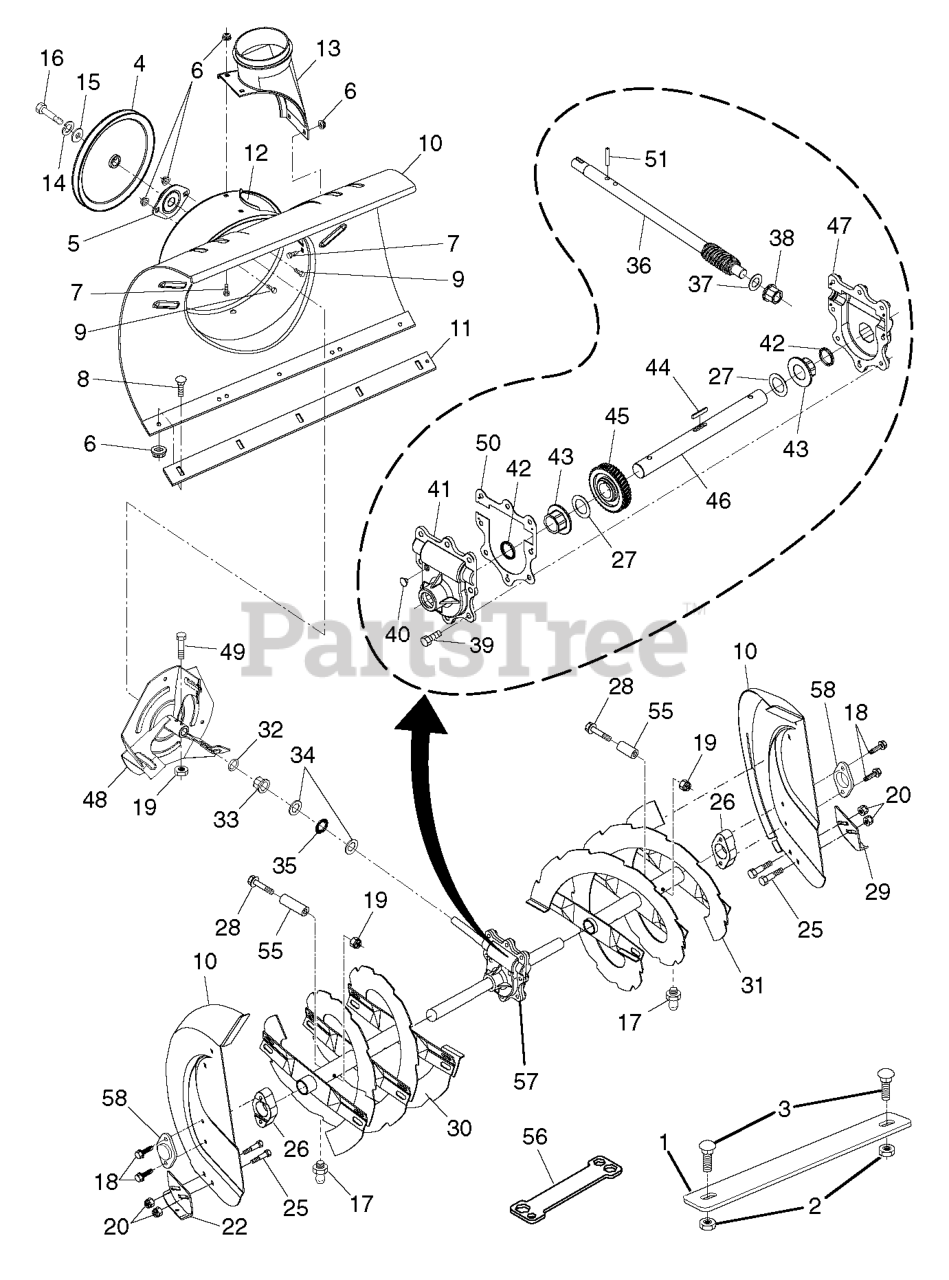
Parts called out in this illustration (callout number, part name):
1	WEIGHT, AUGER HOUSING 27
2	NUT.LOCK.5/16-18
3	BOLT.CARRIAGE.5/16-18
4	PULLEY, IMPELLER
5	BEARING FLANGE
6	NUT, HEX FLANGE 5/16-18
7	BOLT.CARRIAGE.5/16-18X
8	BOLT
10	HOUSING, AUGER
11	BAR, SCRAPER
12	BRACKET, CORNER DISCHARGE
13	BASE DISCHARGE CHUTE
14	WASHER, FLAT
15	WASHER, LOCK 5/16
16	Screw, Hex Head 5/16-18 x 3/4
17	GREASE FITTING
18	SCREW, HEX HD 5/16X1
19	LOCKNUT.NYLOC.1/4-20
20	NUT, HEX FLANGE 5/16-18
22	SKID PLATE RH
25	BOLT
26	BEARING.BALL.AUGER.SHAFT
27	WASHER TRUST 1"
28	BOLT, SHEAR
29	SKID PLATE LH
30	AUGER ASSY-RH
31	AUGER ASSY-LH
33	BUSHING, FLANGE 3/4
34	WASHER, THRUST 3/4
35	BEARING TRUST 3/4 NTA-1220
36	SHAFT, IMPELLER
37	WASHER, THRUST 5/8
38	FLANGE BUSHING-5/8
39	HEX SCREW-5/16 X 3/4
40	CASE PLUG
41	GEARBOX HOUSING-RH
42	OIL SEAL
43	FLANGE BUSHING-1"
44	KEY, SQUARE 1/4 X .875
45	WORM GEAR
46	AUGER SHAFT
47	HOUSING.GEARBOX.LH(SERVICE)
48	IMPELLER ASSY
49	SCREW.HEX.HD1/4-20X
50	GEARBOX GASKET
51	PIN, ROLL 3/16 X 1-1/8
55	SPACER.3943.SLEEVE.250X.47
56	RP WRENCH, SNOWTHROWER
57	GEARBOX.ASSEMBLY.AUGER
58	BEARING RETAINER, PLASTIC
